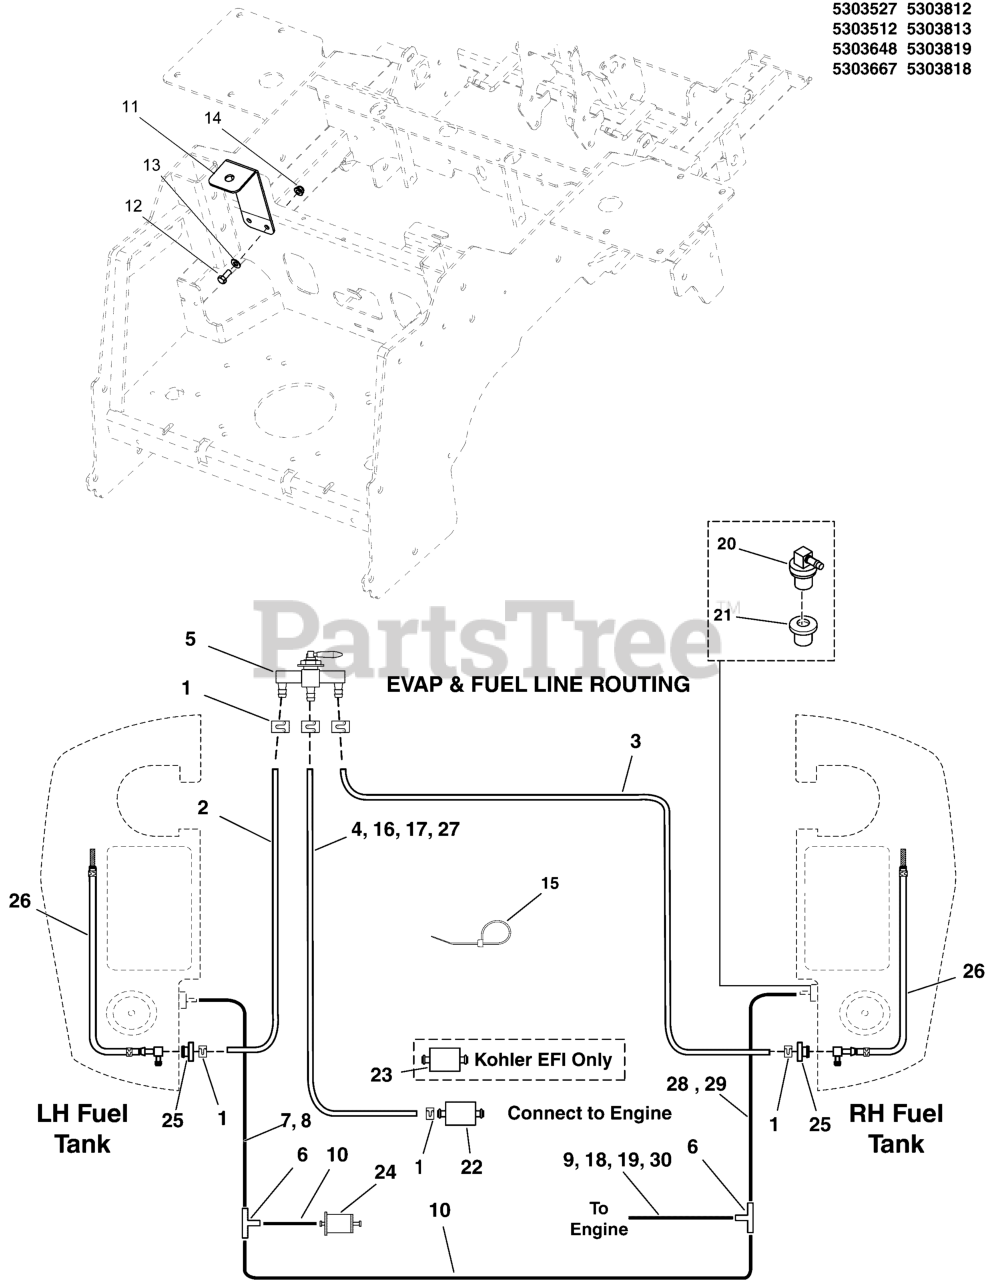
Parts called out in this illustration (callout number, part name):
1	CLAMP, Hose
2	1/4" Fuel Line, 11" Long
3	HOSE, 1/4" FUEL, 27.00"
4	HOSE, 1/4" FUEL, 19.50"
5	VALVE, FUEL STRAIGHT, OUTLET
6	FITTING, 3/16" TEE, BARB TYPE, HDPE
7	HOSE, VAPOR, 5MM ID, 15.50 LG
8	HOSE, VAPOR, 5MM ID, 23.00 LG
9	HOSE, VAPOR, 5MM ID, 32.00 LG
10	HOSE-VAPOR
11	BRACKET, FUEL VALVE, IS2100 - BLK
12	BOLT, 5/16-18 X 3/4 GD5
13	WASHER, 5/16" SAE
14	NUT, 5/16-18 HEX NYLOCK FLANGE NUT
15	TIE, SELF-LOCKING, 12"
16	HOSE, FUEL, 1/4 IN, LW PRMTN, 24" LONG
17	1/4" Fuel Line, 12" Long
18	HOSE, VAPOR, 5MM ID, 16.00 LG
19	HOSE, VAPOR, 5MM ID, 13.50 LG
20	REMOTE VENT ASSEMBLY
21	GROMMET (SV)
22	FUEL FILTER (SV)
23	FUEL FILTER, 29HP KOH, EFI, 25 050 42 (SV)
24	FILTER, FUEL
25	BUSHING-FUEL TANK RED RUBBER
26	PICKUP TUBE ASSEMBLY, FUEL LINE (SV)
27	1/4" Fuel Line, 10" Long
28	HOSE, VAPOR, 5MM ID, 15.50 LG
29	HOSE, VAPOR, 5MM ID, 23.00 LG
30	HOSE, VAPOR, 5MM ID, 23.00 LG
